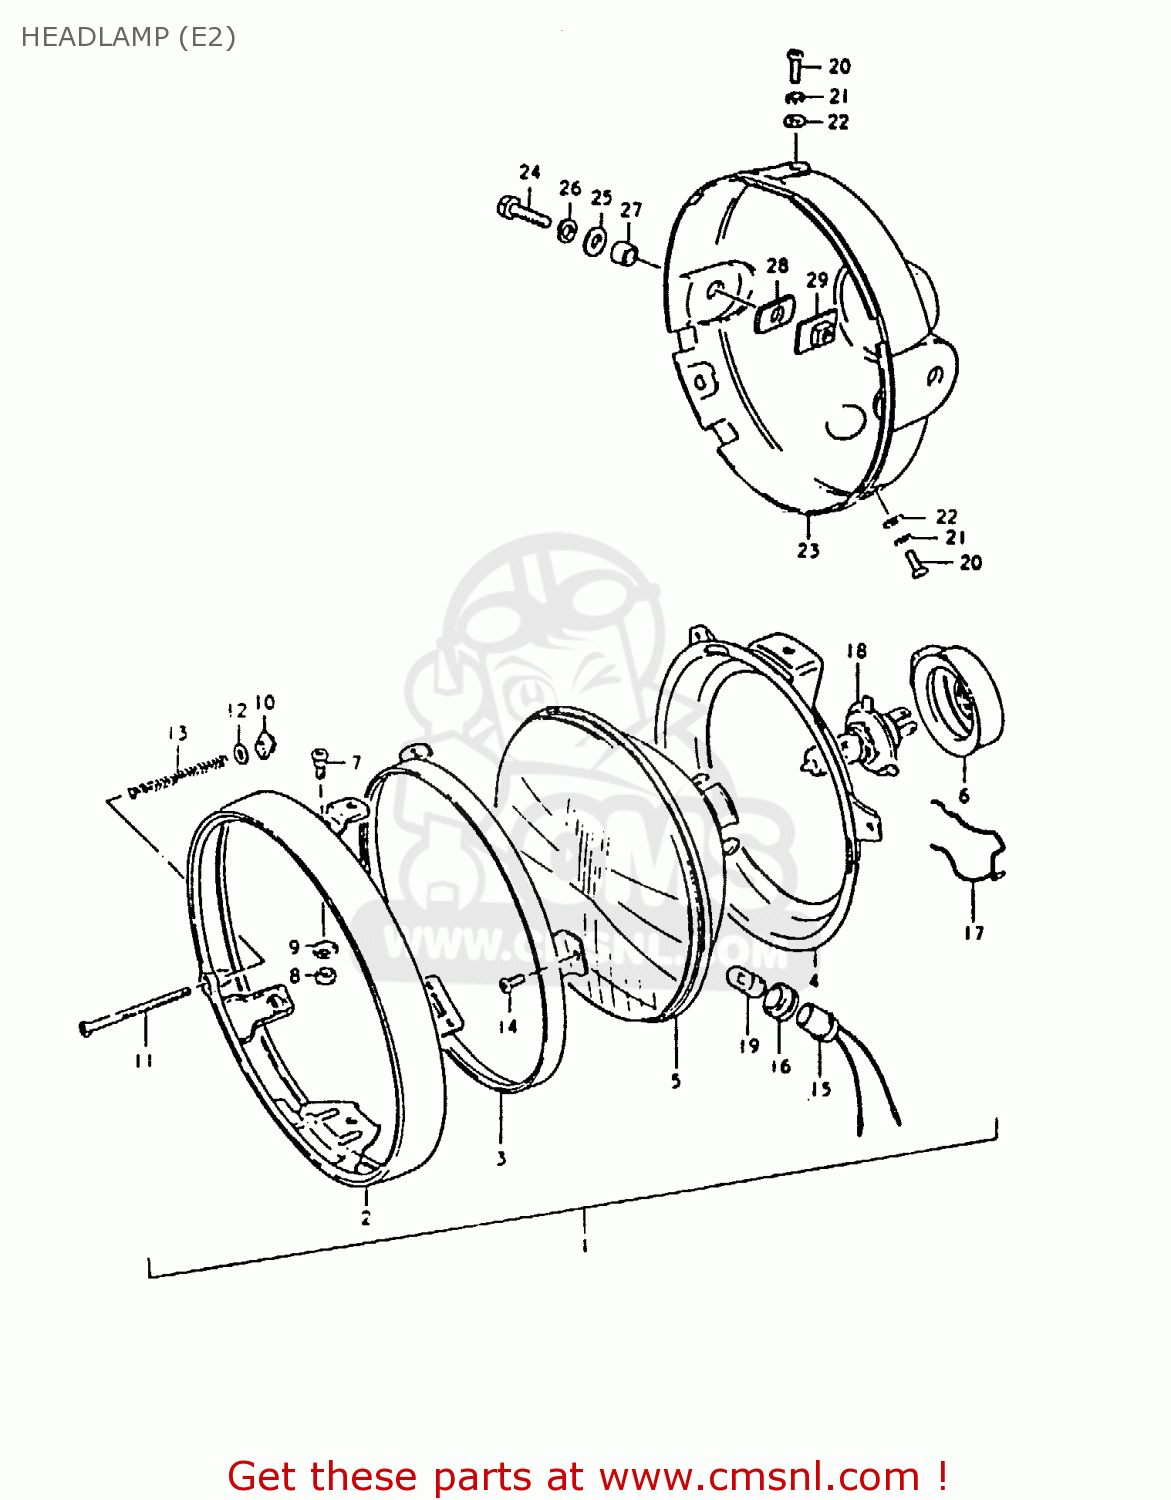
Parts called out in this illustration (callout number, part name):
1	HEADLAMP ASSY
2	RIM
3	RETAINER
4	RING,HEADLAMP UNIT
5	UNIT
6	COVER,HEADLAMP SOCKET
7	SCREW
8	NUT,ADJUSTING
9	SPACER
10	NUT
11	SCREW,HEADLAMP ADJUST
12	WASHER
13	SPRING,HEADLAMP ADJUST
14	SCREW
15	SOCKET
16	JOINT,RUBBER
17	CLAMP,HEADLAMP SOCKET
18	BULB(12V60/55W,H4)
19	BULB(12V4W)
20	SCREW
21	WASHER,LOCK
22	WASHER
23	HOUSING,HEADLAMP(BLACK)
24	BOLT
25	WASHER
26	LOCK WASHER
27	SPACER (8.8X12X7)
28	CUSHION
29	PLATE,HEADLAMP HOUSING
